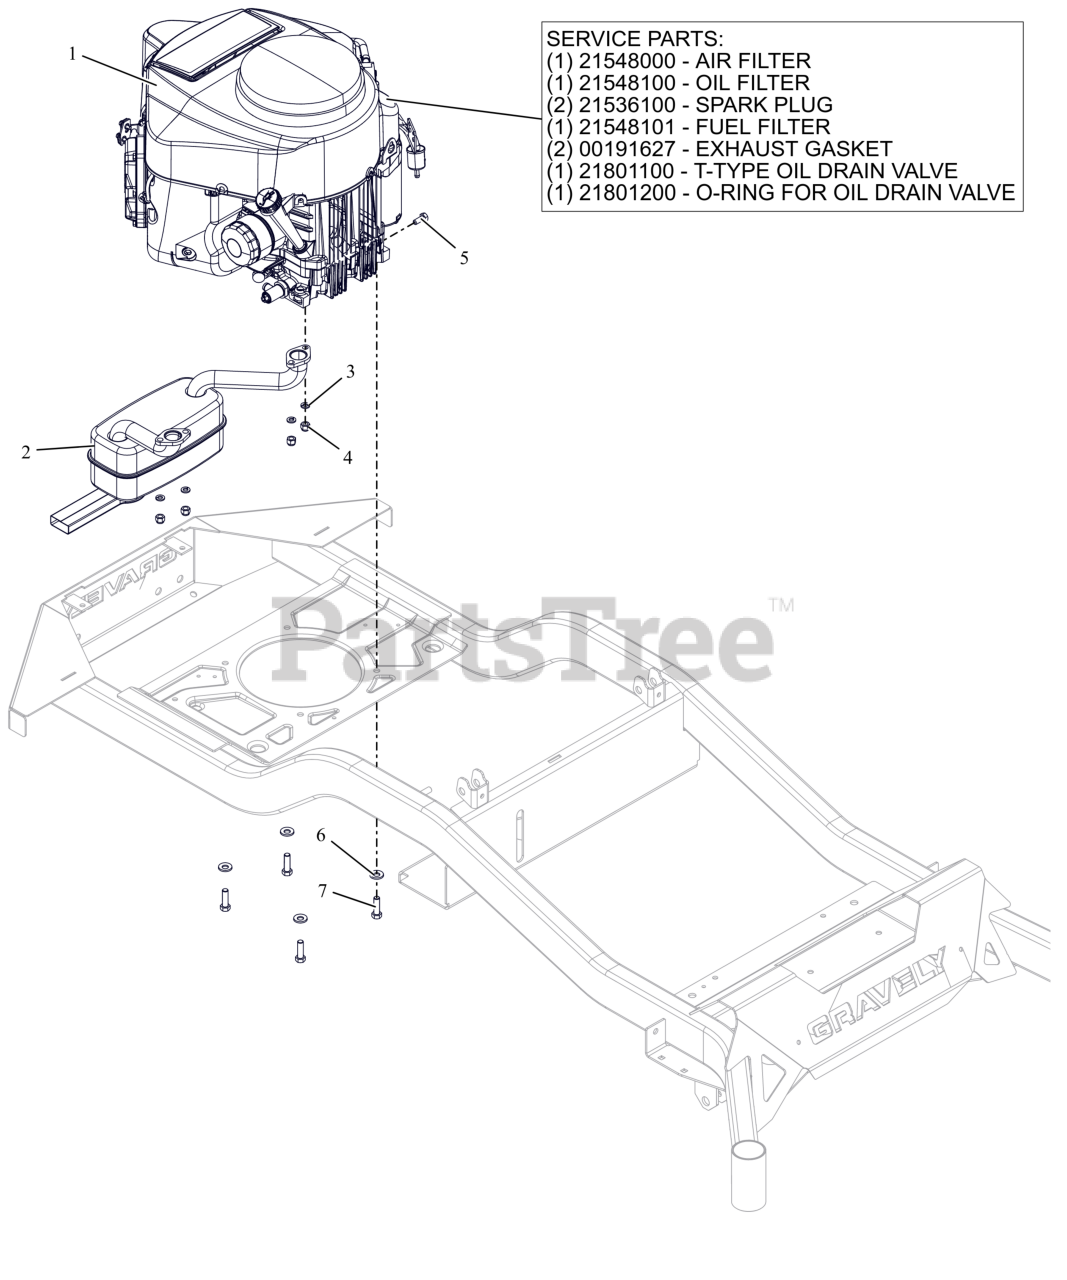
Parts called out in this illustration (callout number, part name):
1	ENGINE, KAWASAKI FR691 23HP
1	AIR FILTER, KAWASAKI FR
1	OIL FILTER, KAWASAKI FR
1	PLUG, SPARK
1	FUEL FILTER-KAWASAKI FR
1	GASKET, MUFFLER S/O
1	VALVE- T-TYPE OIL DRAIN
1	O-RING- OIL DRAIN VALVE
2	MUFFLER, KAWASAKI
3	WSHR,LK-REG .312X.078 ZCC
4	NUT,NYL M8-1.25 G8.8 ZCC
5	BLT, HEX M8-1.25X20 G8.8 ZCC
6	WASHER, 3/8" SPRING DISC
7	BLT, HEX .38-16X1.25 G5 ZCC NT
